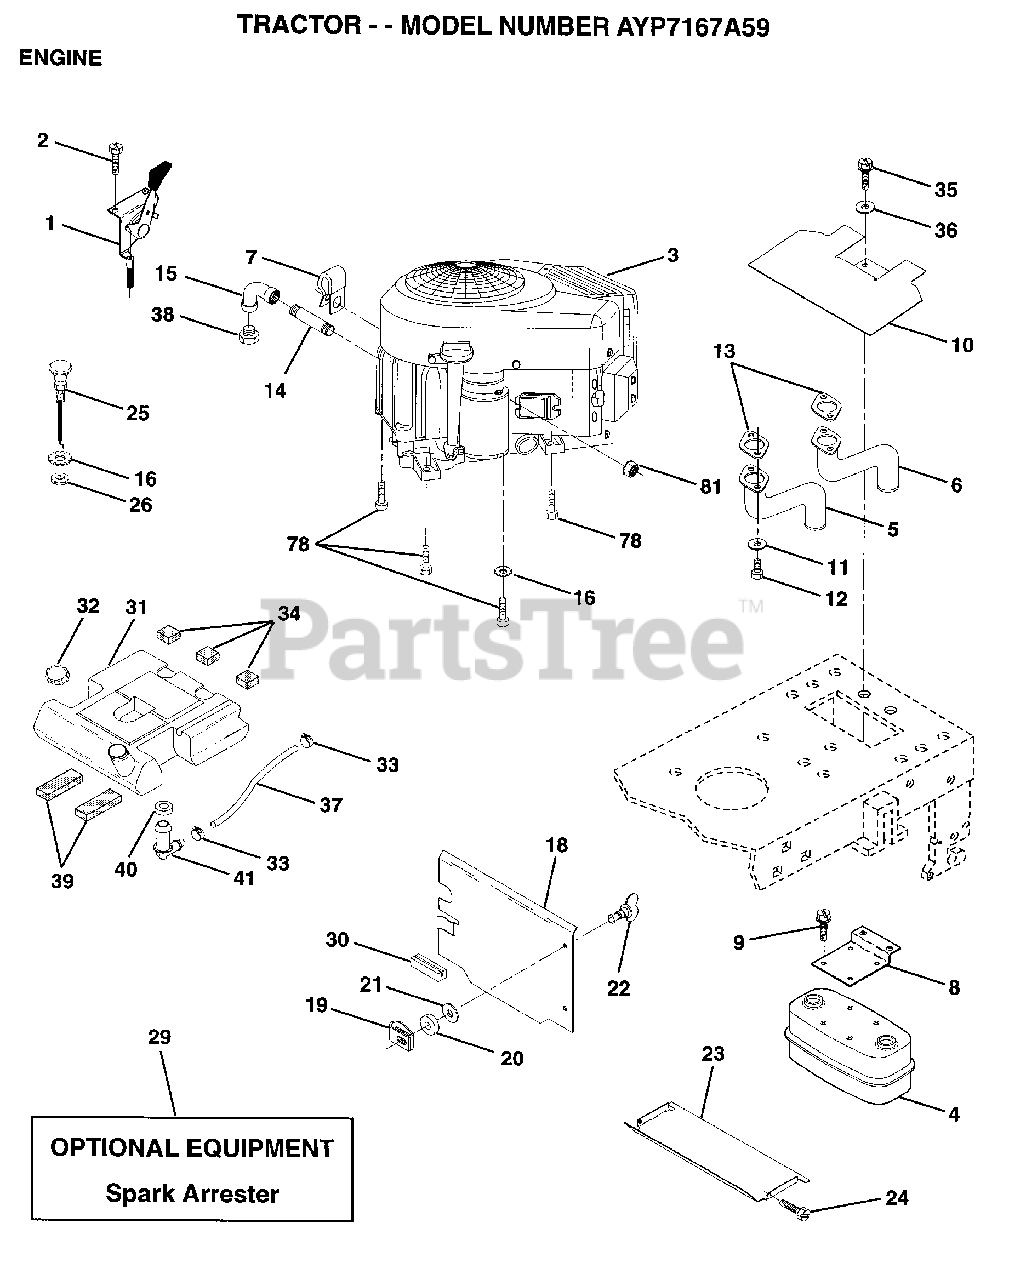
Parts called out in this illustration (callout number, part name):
1	CONTROL THRT 35.5
2	SCREW LT
5	TUBE ASSY EXH LH
6	TUBE ASSY EXH RH
7	CLIP T
8	BRACKET MUFFLER
9	SCREW ST
10	SHIELD.HEAT.
14	PIPE NIPPLE LT
15	ELBOW
16	LOCKWASHER
18	SHIELD HEAT
19	RECEPTACLE LT
20	RETAINER LT
21	WASHER
22	STUD.1/4.TURN
23	HEAT SHIELD
24	SCREW
25	CONTROL.CHOKE.37
32	CAP ASM FUEL
33	HOSE CLAMP
34	PAD-SPACER LT
35	SCREW
36	WASHER
37	FUEL LINE T
39	PAD IDLER TI
40	BUSHING OUTLET T
78	SCREW
81	NUT
